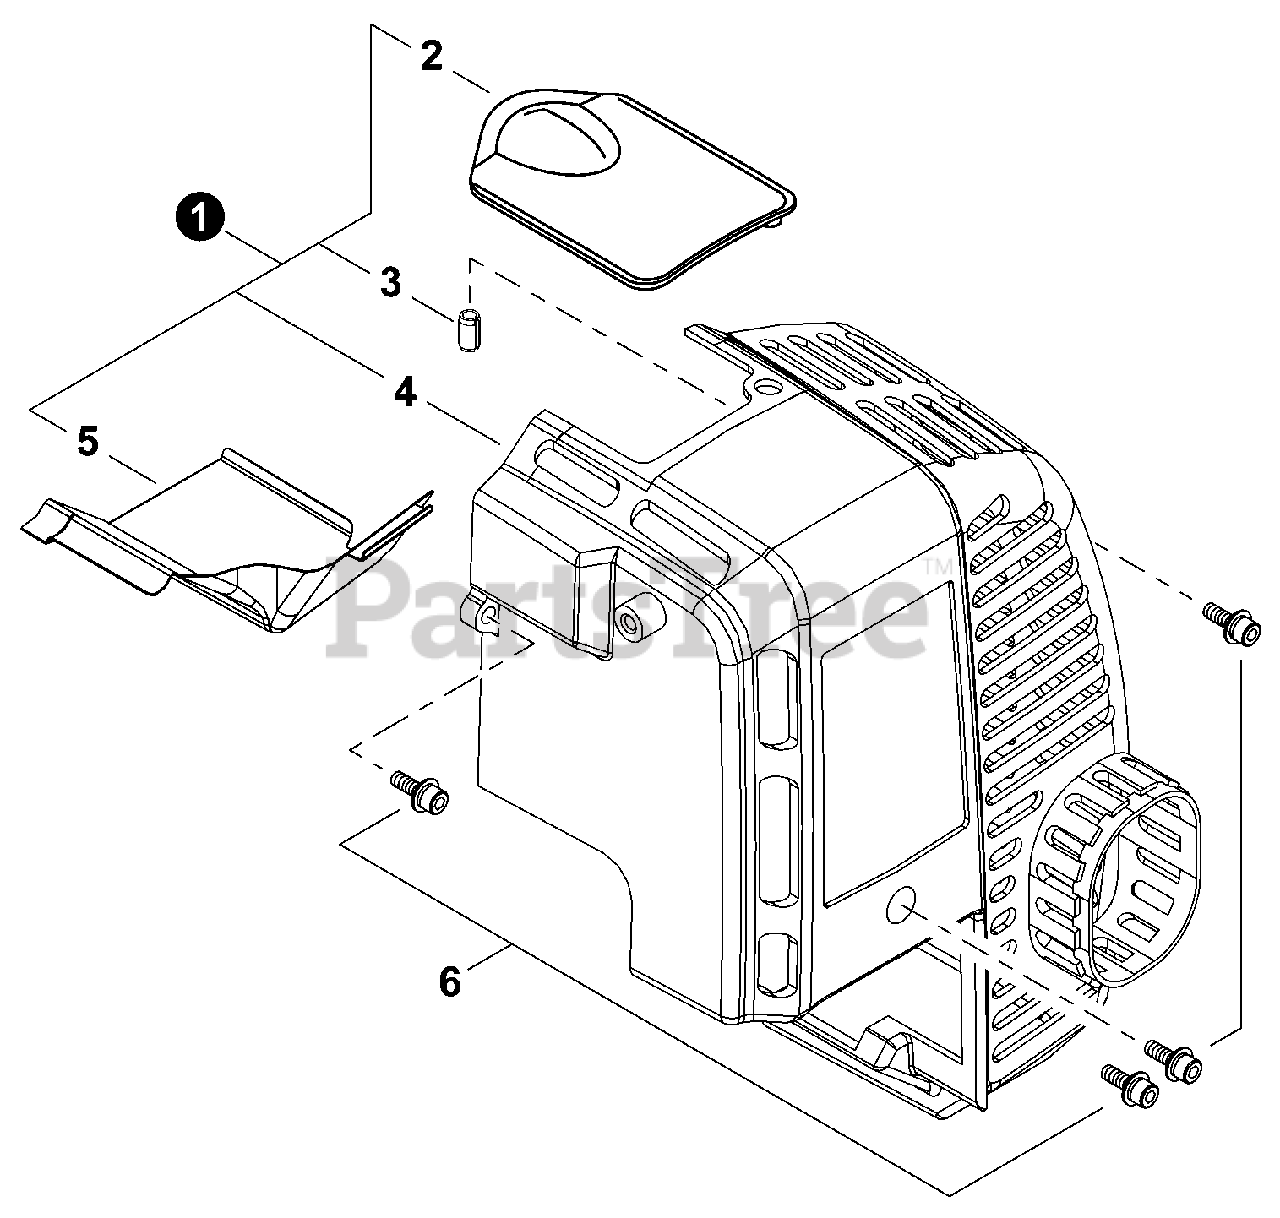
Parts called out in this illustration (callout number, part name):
1	COVER ASSY, ENGINE
2	COVER, SPARK PLUG
3	PIN, SPRING 4×8
4	COVER, ENGINE
5	HEAT SHIELD, EXHAUST
6	BOLT M5×16
